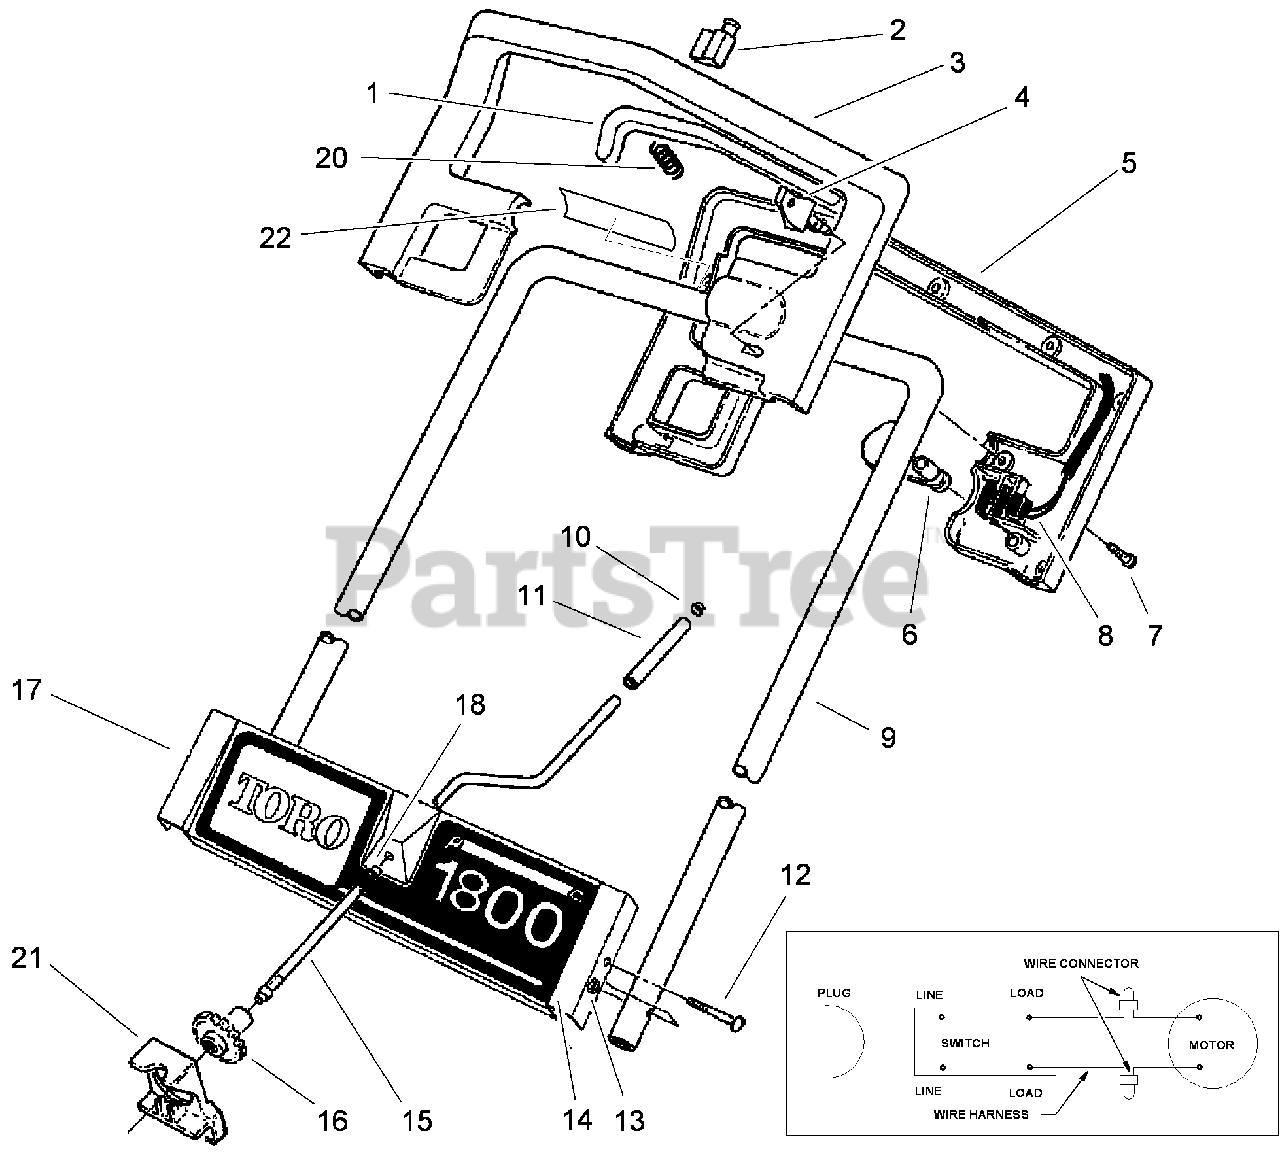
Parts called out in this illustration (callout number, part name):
1	Bar-Switch
2	SWITCH
3	Handle-Control, Upper
5	Handle-Control, Lower
6	Tab-Lock
7	SCREW-PPH
8	Cord-Supply
9	Tube-Handle, Upper
10	PUSHNUT-CAP, WASHER
11	Sleeve-Crank, Chute
12	Screw-HH
13	NUT-LOCK, NI
14	Decal-Escutcheon
15	Rod-Crank, Chute
16	Gear-Crank, Chute
17	Plate-Escutcheon
18	Bushing-Nyliner
21	Brake-Gear
22	Decal-Operation
